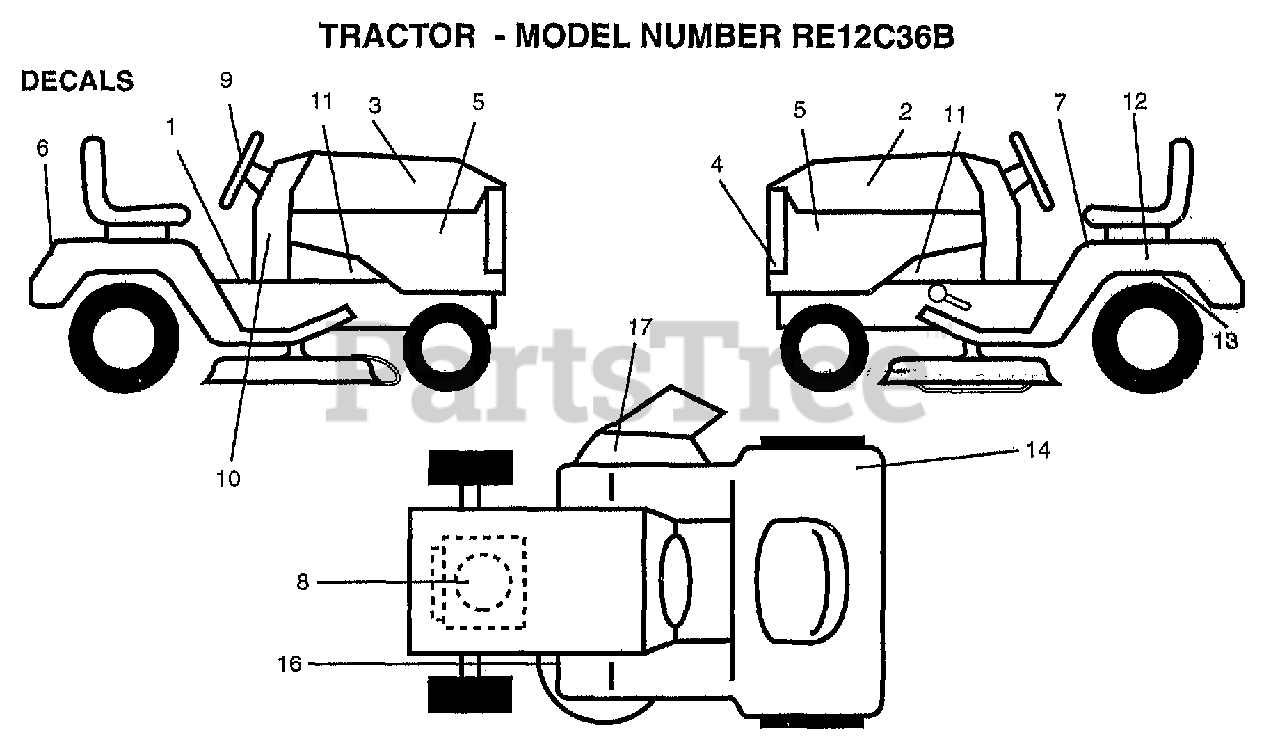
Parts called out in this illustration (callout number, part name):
1	DECAL CLUTCH/BRAK
2	DECAL HD RLY LH
3	DECAL HD RLY RH
4	GRILL DECAL
5	DECAL.INSERT.HOOD
6	FENDER DECAL
7	DECAL.READ.O.MANU
9	"DECAL,STR WHL"
10	DECAL.EURO.ST.CE.
11	"DECAL CHASSIS,HOT"
12	DECAL.BATRY.3-3908
13	DECAL.DRAWBAR.LDL
16	DECAL.DANGER.CUTF
17	DECAL.V.BELT
